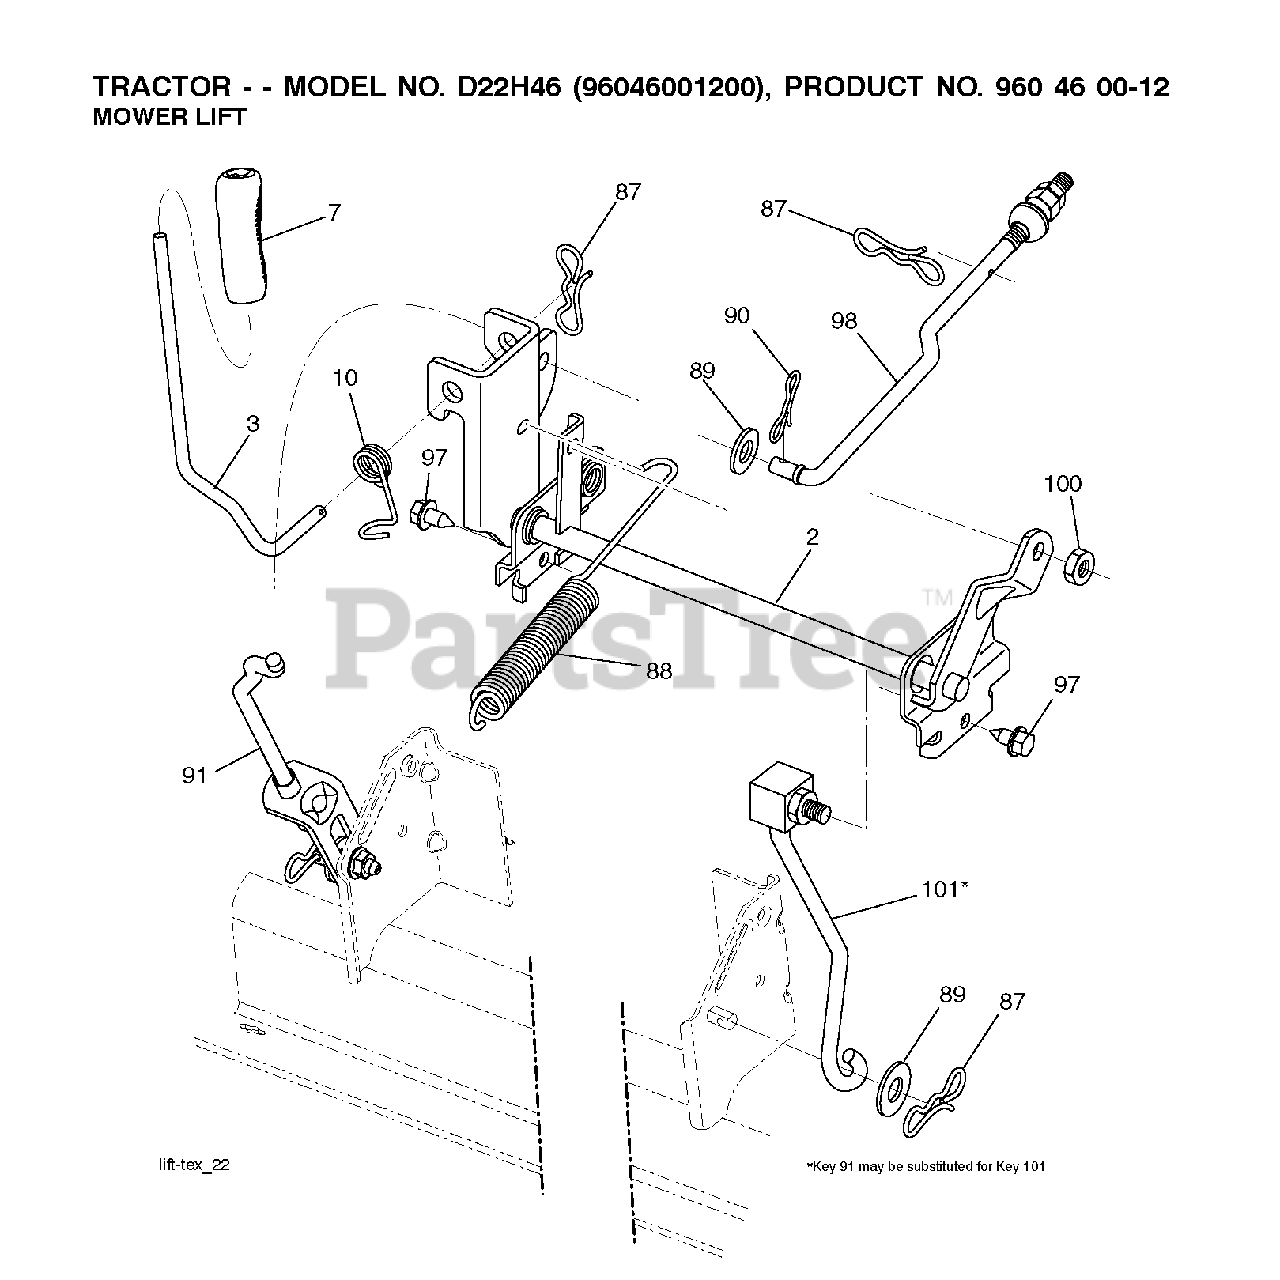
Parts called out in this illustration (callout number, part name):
2	SHAFT.ASM.CROSS.LIFT
3	LEVER.LIFT.HANDLE.LT
7	GRIP.HANDLE.LIFT.PVC.BLACK
10	SPRING.TORSION.LIFT.HANDLE
87	PIN.COTTER.7/16.BOW TI.
88	SPRING.LIFT.ASSIST
89	GRIP.HANDLE.LIFT.PVC.BLACK
90	PIN.COTTER.5/16.BOW TI
91	LINK.ASM.LIFT.REAR
97	SCREW, 3/8-16X3/4
98	LINK.ASM.SUSP.FRONT.MW
100	LINK.ASM.LIFT.FIXE.38/42/46"
101	LOCKNUT
